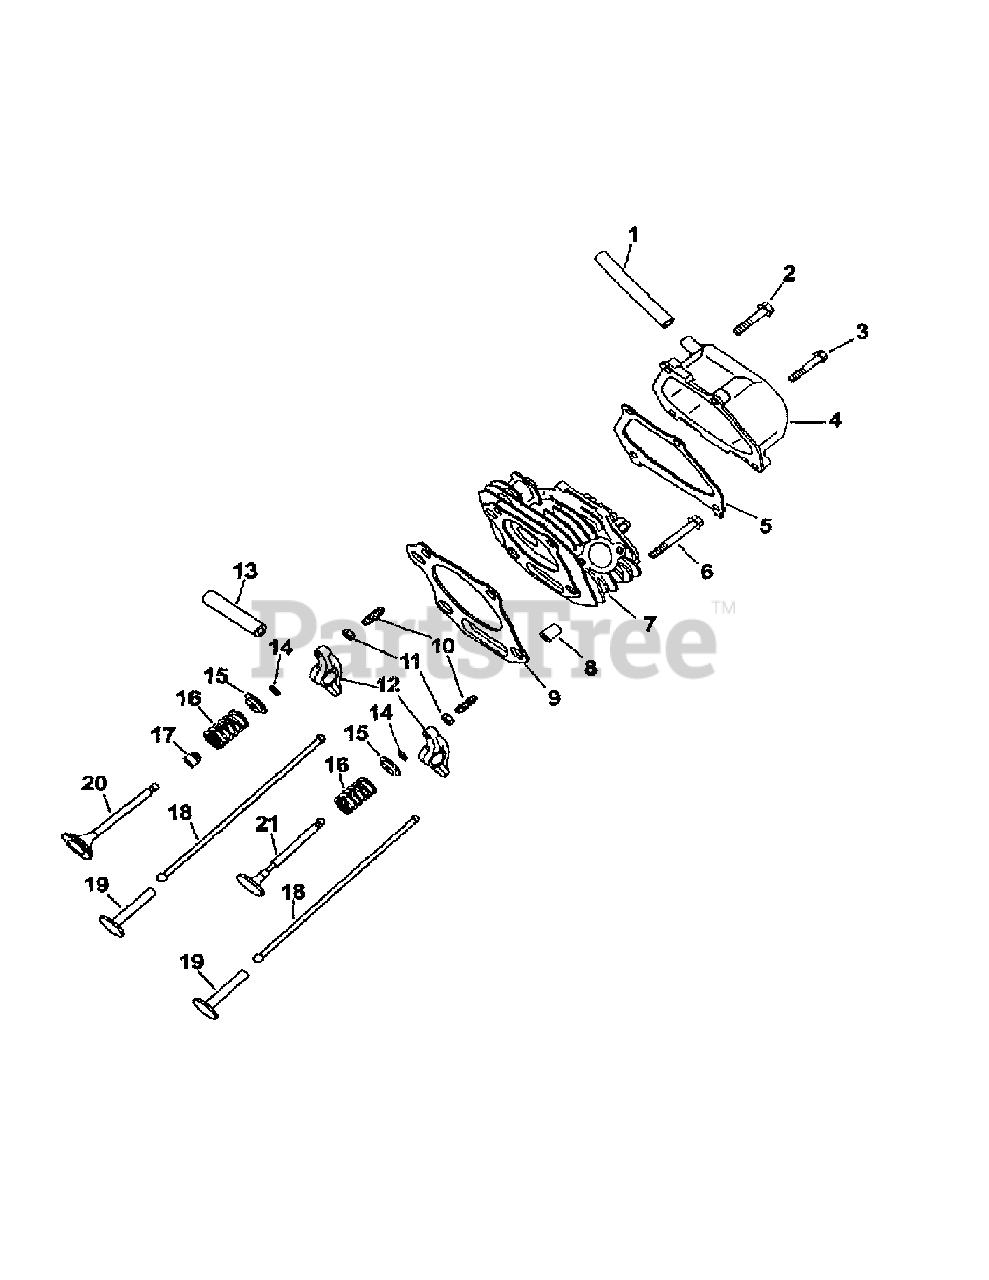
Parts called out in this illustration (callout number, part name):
1	Hose, Breather
2	Screw, Valve Cover
3	Screw, Valve Cover
5	Gasket, Valve Cover
6	Screw, Cylinder
7	Head, Cylinder
10	Screw, Valve Adj.
12	Arm, Rocker
13	Shaft, Rocker Arm
14	Keeper, Valve
15	Cap, Valve Spring
16	Spring, Valve
17	Seal, Vaqlve Stem
18	Rod, Push
20	Valve, Intake
21	Valve, Exhaust
